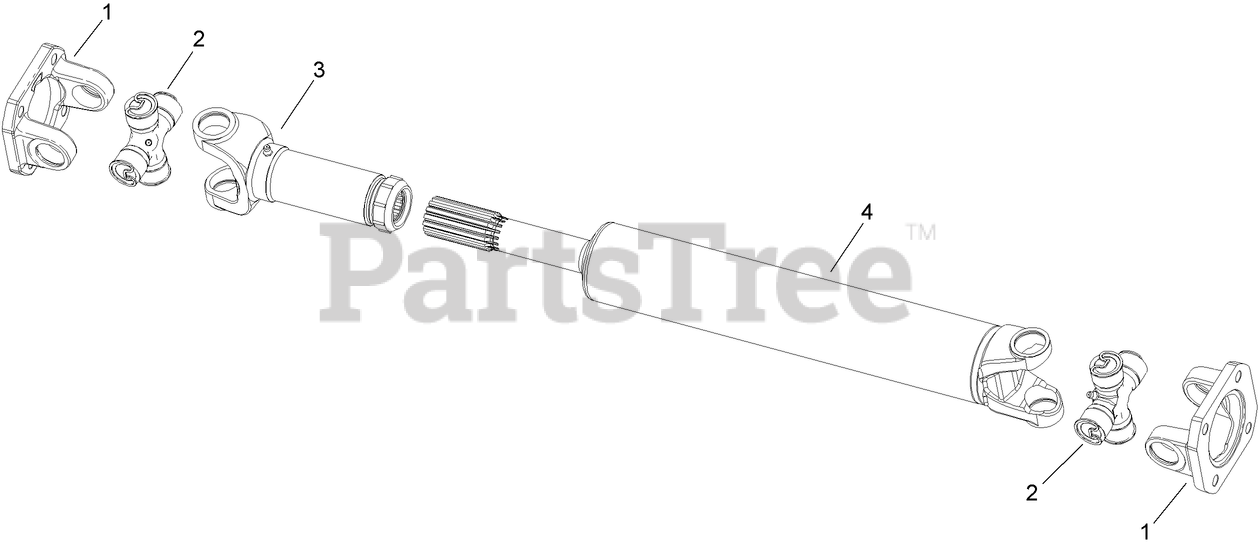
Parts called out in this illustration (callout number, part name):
1	FLANGE-YOKE
2	JOINT-UNIVERSAL
3	SLIP-YOKE
4	YOKE, TUBE AND STUB ASM
